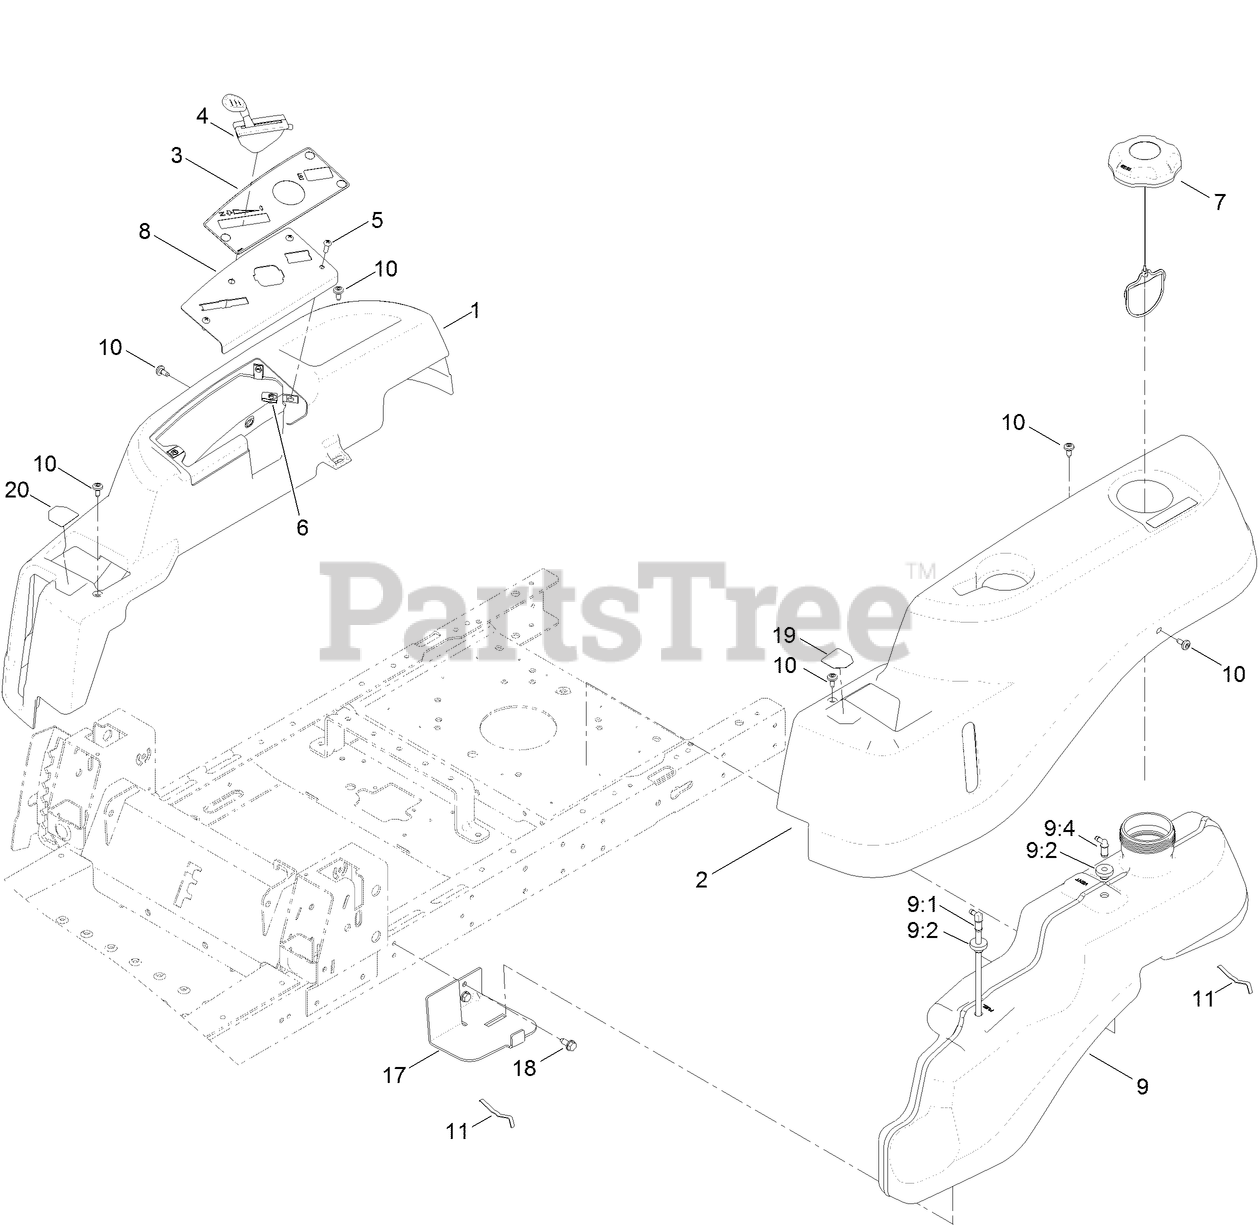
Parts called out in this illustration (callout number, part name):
1	POD-RH
3	DECAL-PANEL, CONTROL
4	CABLE-THROTTLE AND CHOKE
5	SCREW-PRH
8	PLATE-CONTROL
9	FUEL TANK ASM
9:1	CONNECTOR-ELBOW, 90 DEG
9:2	BUSHING
9:4	FITTING-PLASTIC
10	SCREW-SHOULDER
11	SPRING
17	SUPPORT-TANK, FRONT
18	SCREW-HWHTF
19	DECAL-LEVER, CONTROL (LH)
20	DECAL-LEVER, CONTROL (RH)
